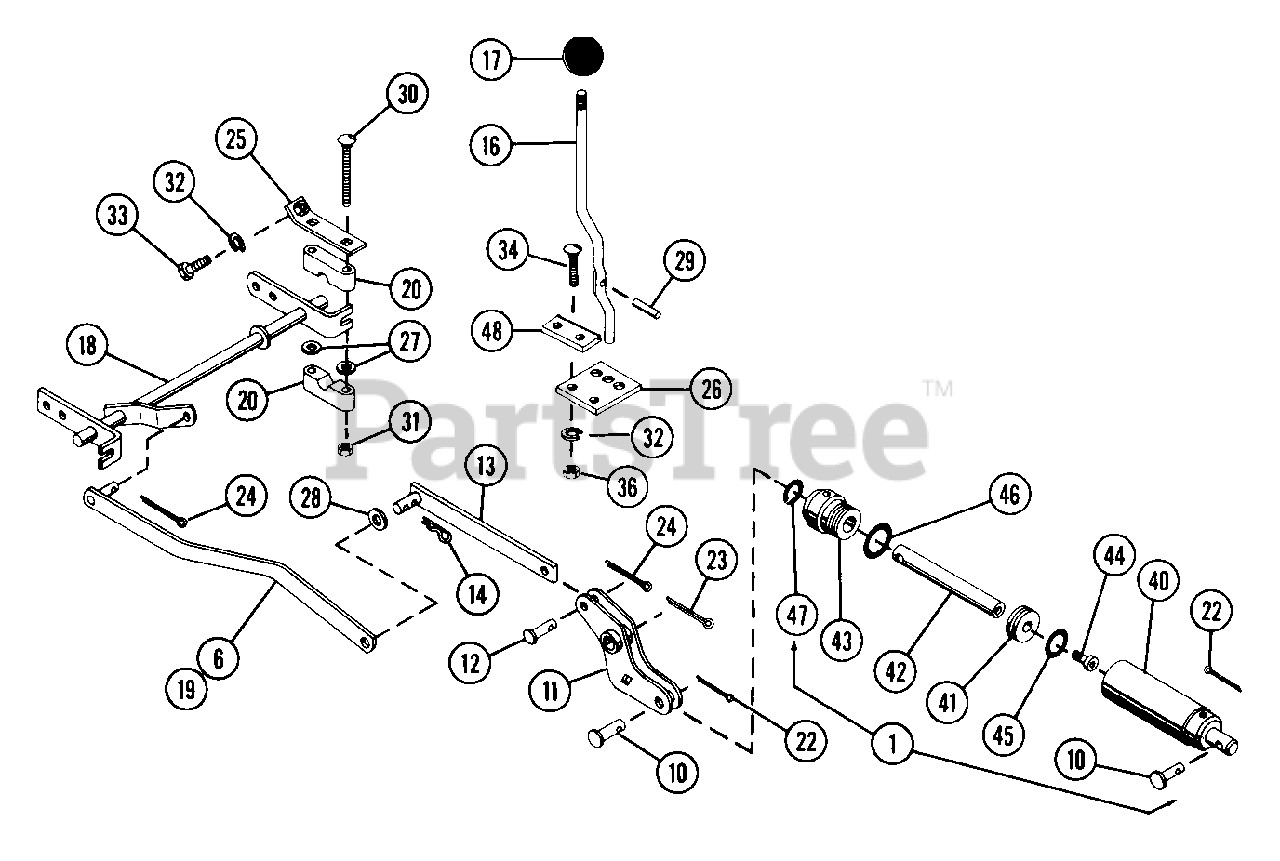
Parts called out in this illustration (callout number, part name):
1	CYLINDER ASSEMBLY
2	CONTROL VALVE
2	HYDRAULIC CONTROL VALVE
3	HYDRAULIC HOSE
4	HYDRAULIC HOSE
5	HYDRAULIC HOSE
6	CONNECTOR LINK
7	ADAPTER 45 9/16 TO 1/4
8	BLT-HEX .25-20X1.50 PL GR5
9	WSHR-FL-STL.281X.62X.065 PL
10	PIN-CLEV .494X1.94 YWZC
11	BELLCRANK
12	RVT-BTN .62X1.50 SPL
14	PIN-HAIR INT .09X.188 PL
15	WSHR-LK .250X.077 HVY PL
16	CONTROL ROD
17	KNOB-STEERING LOCK
18	FRONT ROCK SHAFT SERVICE ASSEM
19	FRONT ROCK SHAFT CONNECTOR LIN
21	NUT-HEX .250-20 PL
22	PIN-COTR .12X1.0 PL
23	PIN-COTR .18X1.25 PL
24	PIN-COTR .18X1.0 PL
26	PIVOT BRACKET
27	WSHR-FL-STL .406X.750X.005
28	WSHR-FL-STL.812X1.500X.139
29	PIN-GRV .250X.75 TP B PL
30	BLT-RDHDSQNK .38-16X2.25 SHTPL
31	NUT-LK-CTR .375-16 GR A PL
32	WSHR-LK .312X.097 PL HVY
33	BLT-HEX .31-18X1.25 PL GR5
34	BLT-RDHDSQNK .31-18X1.25 SHTPL
35	WSHR-FL-STL .38X.875X.083 PL
36	NUT-HEX .312-18
38	CONNECTOR
39	LOWER HOUSING
40	CYLINDER
43	ROD CAP
44	SCR-SKH .38-24X1.00
45	O-RING 1.625X2.000
46	O-RING 1.937X2.125
47	O-RING 1.000X1.250X
